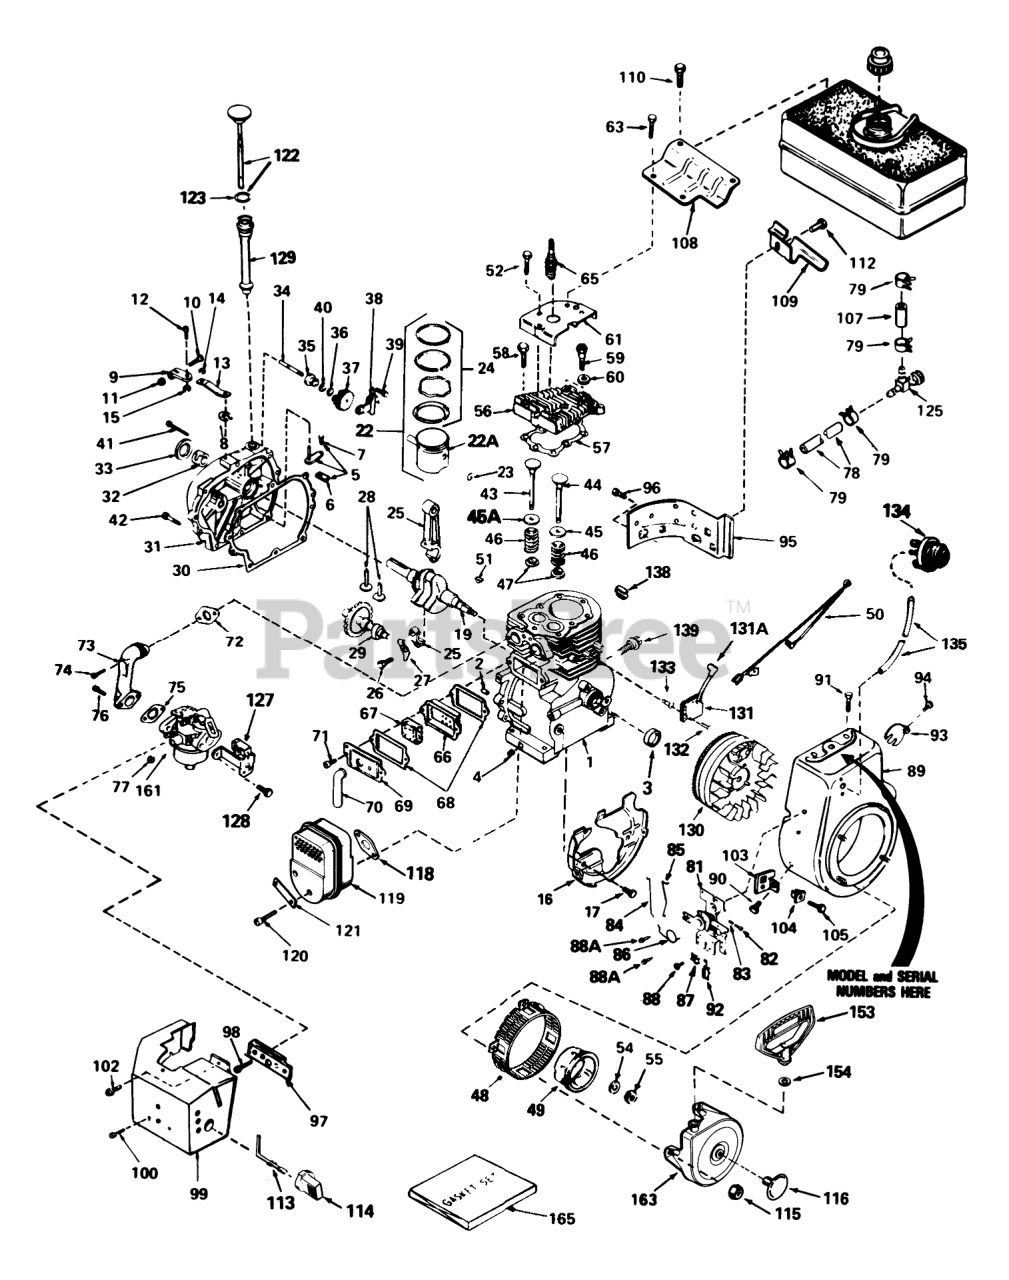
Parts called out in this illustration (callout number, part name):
1	Cylinder ASM
2	Pin-Dowel
3	Seal-Oil
4	Plug-Drain, Oil (SQH 1/4-18)
5	Rod Assy., Governor (Incl. Ref. #6 & 7)
6	Yoke-Governor
7	Screw (6-40x5/16)
8	Ring-Retaining
9	Clamp-Lever, Governor
11	Nut-Lock
12	Screw
13	Lever-Governor
14	Washer-Lock
15	Nut-Lock
16	Baffle-Blower Housing
17	Screw (1/4-20x19/32)
19	Crankshaft
22	Piston, Pin & Ring Assy. (Std.) (Incl. Ref. #22A, 23 & 24)
22	Piston, Pin & Ring Assy. (Incl. Ref. #22A, 23 & 24)
22A	Piston & Pin Assy. (Std.) (Incl. Ref. #23)
22A	Piston & Pin Assy. (Incl. Ref. #23)
23	Ring-Retaining, Piston Pin
24	Ring Set (Std.)
24	Ring Set (.010" OS)
24	Ring Set (.020" OS)
25	Rod Assy., Connecting (Incl. Ref. #26 & 27)
26	Bolt-Rod
27	Dipper-Oil
28	Lifter-Valve
29	Camshaft (MCR)
30	Cylinder Cover Gasket
31	Cover, Cylinder (Incl. Ref. #32, 33 & 34)
32	Bushing-Crankshaft
33	Seal-Oil
34	Shaft-Governor
35	Spool-Governor
36	Ring-Retaining
37	Gear Assy., Governor (Incl. Ref. #40)
38	Bracket-Gear, Governor
39	Screw (10-24x1/2)
40	Washer-Flat
41	Screw (1/4-20x1-3/16)
42	Screw (1/4-20x1-11/16)
43	Valve, Intake (Std.) (Incl.Ref. #47)
43	Valve, Intake (1/32" oversize) (Incl. Ref. #47)
44	Valve, Exhaust (Std.) (Incl. Ref. #47)
44	Valve, Exhaust (1/32"oversize) (Incl.Ref. #47)
45	Cap-Spring, Valve
45A	Seal-Intake Valve
46	Spring-Valve
47	Keeper-Spring, Valve
48	Screen-Starter
49	Cup-Starter
50	Ground Wire
51	Key-Flywheel
52	Screw (1/4-20 X 5/8)
54	Washer-Belleville
55	Nut-Flywheel
56	Head Cylinder
57	Gasket-Cylinder Head
58	Screw (5/16-18x1-1/2)
59	Screw (5/16-18x1-25/32)
60	Washer-Flat
61	Cover-Cylinder Head
63	Screw
65	Spark Plug-Resistor (R J19 L M)
66	Body-Breather
67	Element-Breather
68	Gasket-Breather
69	Cover-Valve
70	Tube-Breather
72	Gasket-Intake
73	Pipe-Intake
74	Screw (T-30, 5/16-18x1-3/32)
75	Gasket-Carburetor To Intake Pipe
76	Screw (1/4-28x1)
77	Nut and Lock Washer (1/4-28)
78	Line-Fuel
79	Clamp-Line, Fuel
81	Control Assy., Speed (Incl. Ref. #82, 83, 86 & 92)
82	Screw
83	Spring-Compression
84	Link-Governor
85	Link-Throttle
86	Spring-Throttle
87	Conduit
88	Screw (10-32 x 3/8)
88A	Screw (10-32 x 1/2)
89	Housing-Blower
91	Screw (5/16-18x3/4)
92	Terminal
94	Screw (8-32 x 3/8)
95	Extension-Housing, Blower
97	Bracket-Carburetor
98	Screw (8-32x27/64)
99	Cover-Carburetor
100	Screw (10-32 x 3/8)
102	Screw (10-32x1/2)
103	Bracket
104	Grommet
105	Screw
107	Line-Fuel (8.62)
108	Bracket-Tank, Fuel (Black)
109	Bracket-Tank, Fuel
110	Screw (1/4-15x7/8)
112	Screw (1/4-20x19/32)
113	Rod-Choke
114	Knob-Control
115	Nut and Lock Washer (1/4-28)
116	Plug Starter
118	Gasket Exhaust
119	Muffler
120	Screw
121	Plate-Locking
122	A Dipstick, Oil (Incl. Ref. #123)
125	Valve-Shut Off
127	Bracket-Choke
128	Screw (10-32 x 1/2)
129	Tube Fill
130	Flywheel (W/Ring Gear)
131	Solid State Assy. (Incl. Ref. #131A)
131A	Cover, Spark Plug
132	Screw
133	Stud
134	Primer Assy.
135	Line-Primer
138	Clip-Wire
139	Screw (1/4-20x1/2)
153	Handle-Starter, Mitten Grip
161	Carburetor (Incl. Ref. #75)
163	Starter-Rewind
165	Gasket Set
